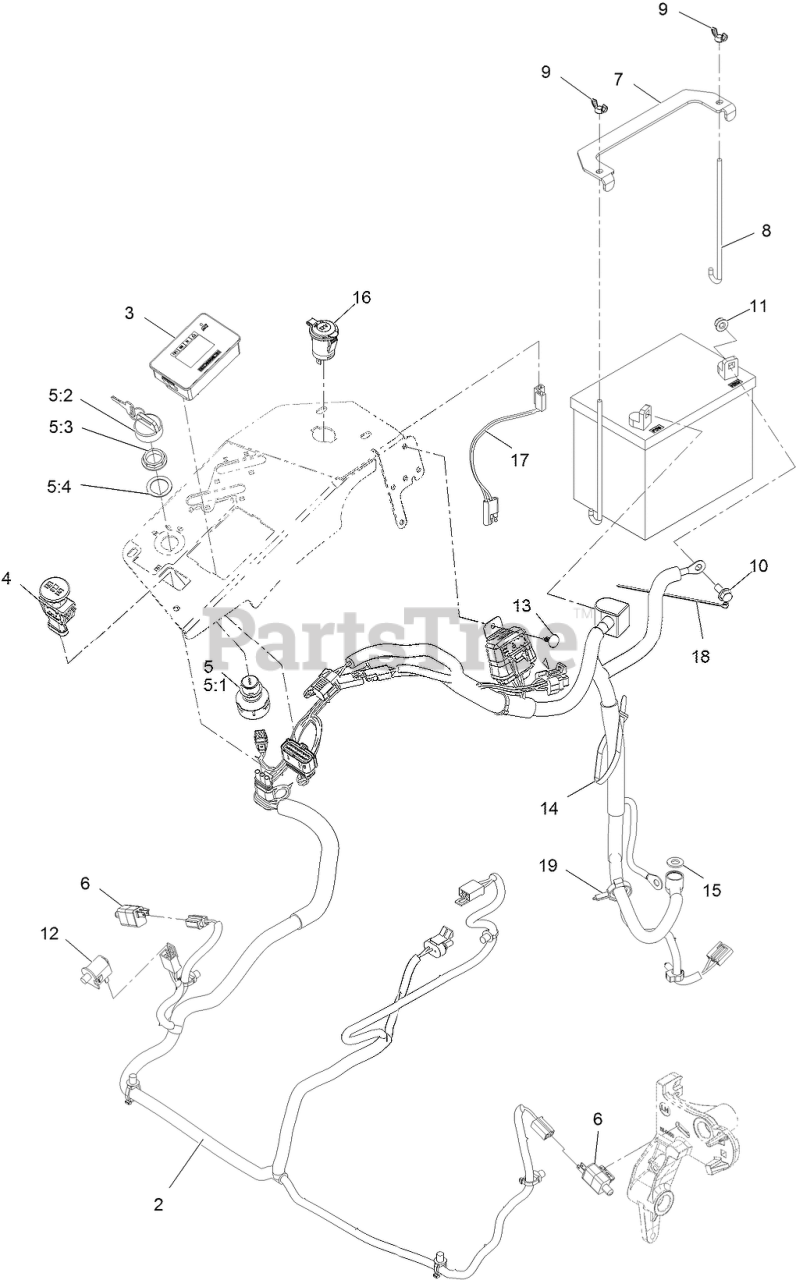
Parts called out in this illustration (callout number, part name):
2	WIRE HARNESS ASM
3	Meter-Hour
4	SWITCH-PTO, SEALED
5	IGNITION SWITCH ASM
5:1	Switch-Ignition
5:2	NUT-MOUNTING
5:3	IGNITION KEY SET
5:4	WASHER-BACKUP
7	STRAP-TIE DOWN, BATTERY
8	BOLT-HOLDDOWN
9	WINGNUT
10	SCREW-HHF
11	NUT-HF, NI
12	SWITCH-BAIL
13	PLUG-PLASTIC
14	TIE-PLASTIC
15	WASHER-FLAT
16	PORT-POWER, 12V
17	HARNESS-RECEPTACLE, 12V
18	TIE-CABLE
19	CLAMP-HOSE
